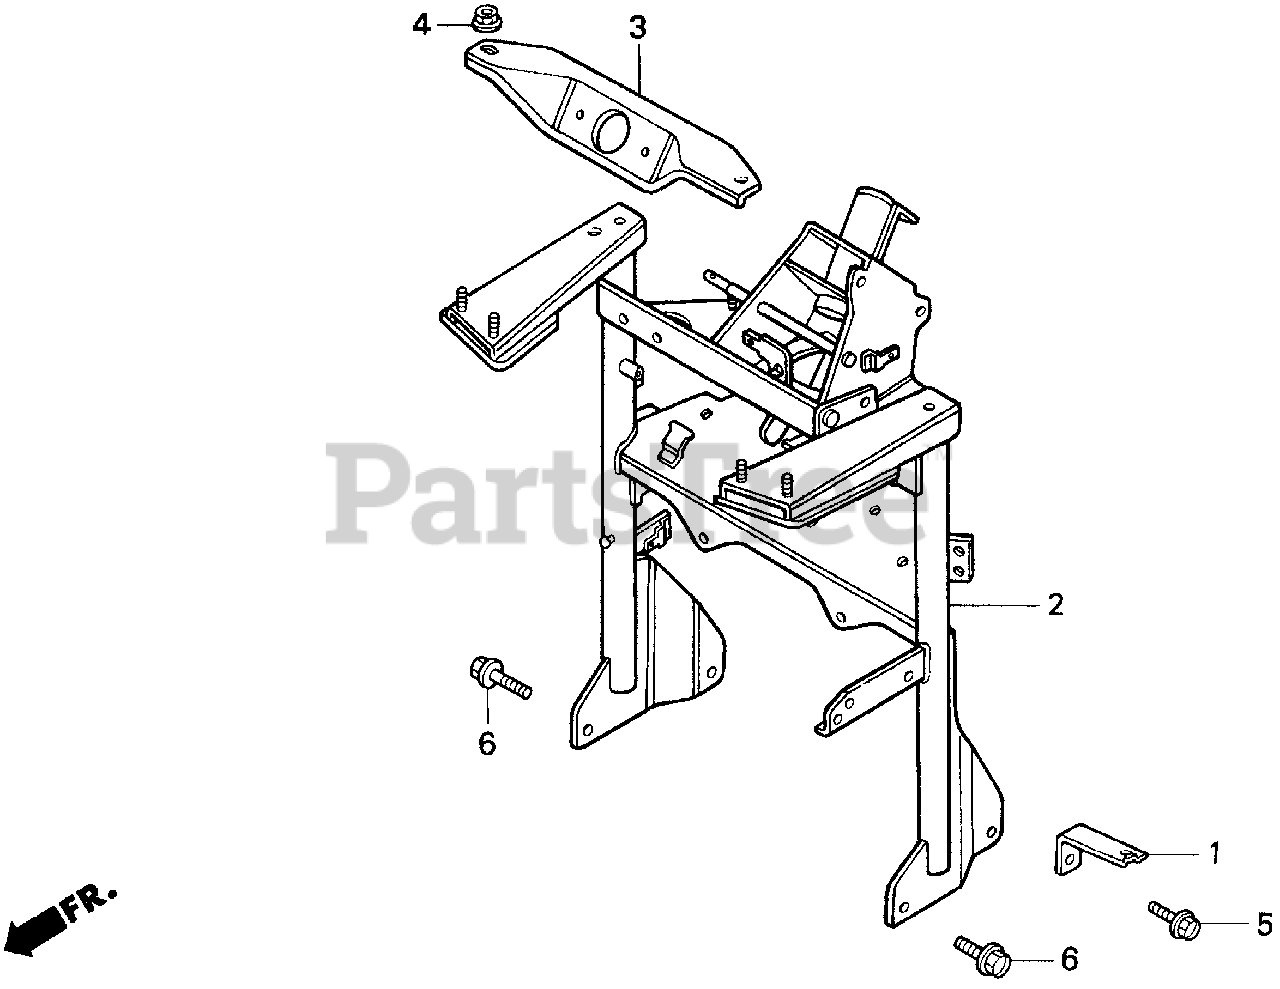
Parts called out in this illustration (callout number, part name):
1	PLATE, TUBE CLAMP EXTENSION
2	COLUMN, STEERING
3	BRACKET, HOOD LOCK
4	NUT, FLANGE (6MM)
5	BOLT, FLANGE (6X12)
6	BOLT, FLANGE (10X16)
